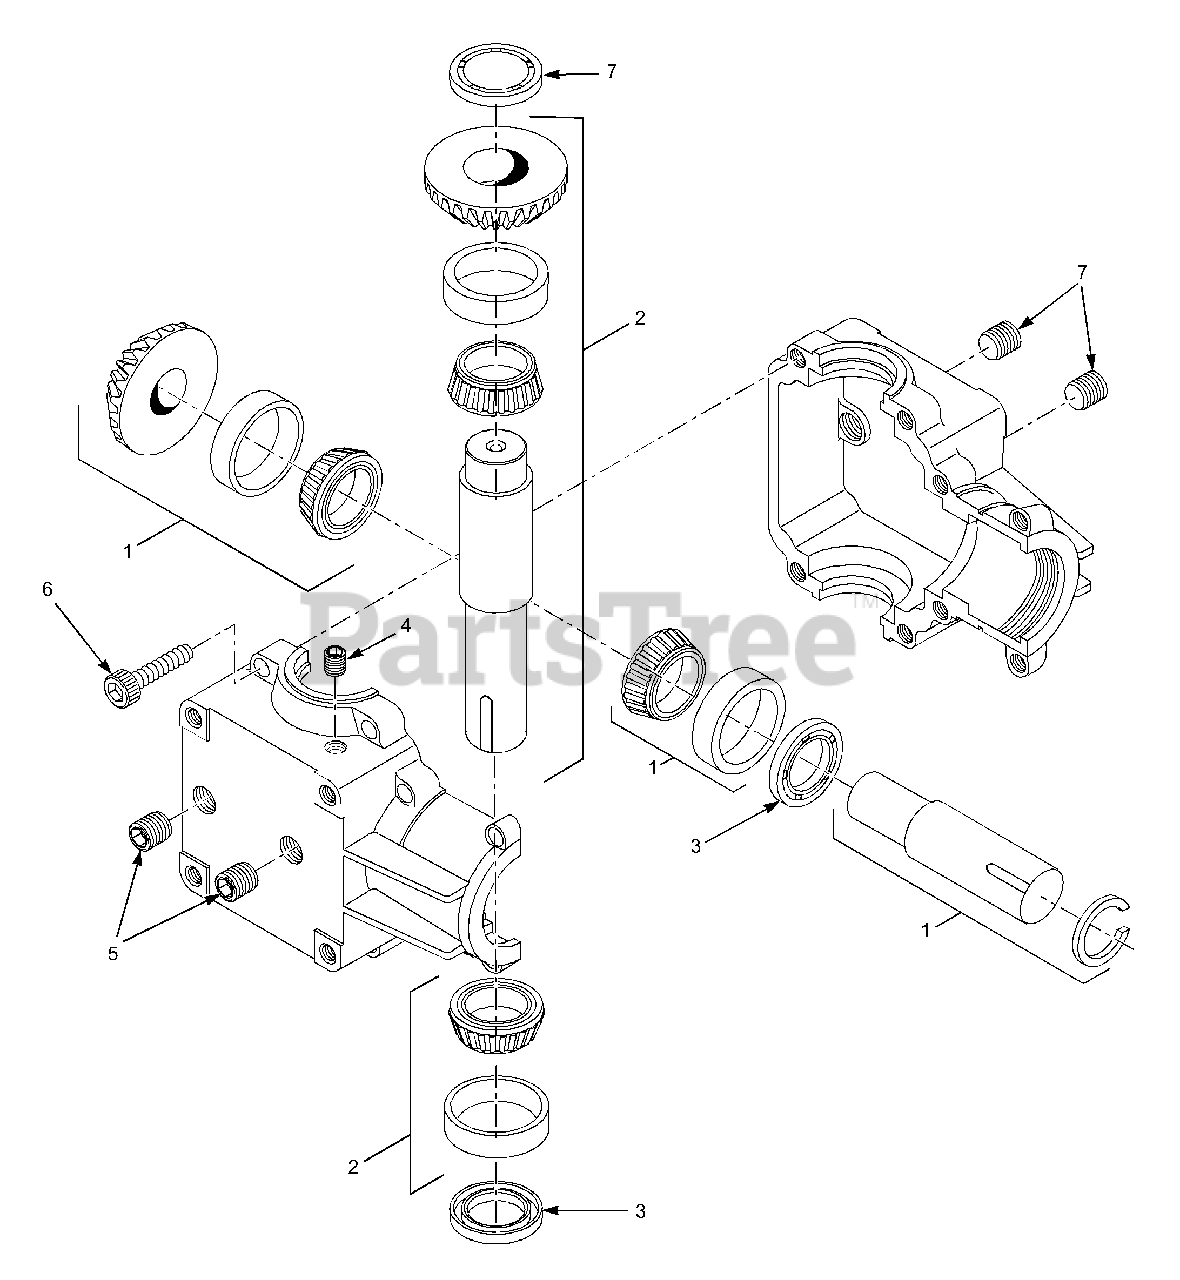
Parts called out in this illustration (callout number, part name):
1	Shaft Assembly
2	Shaft Assembly
3	Seal, 1.00" x 1.50" x 3/16"
4	Plug, 1/8" NPT Socket Head
5	Plug, 1/4" NPT Socket Head
6	Bolt, 5/16-18 x 1.25"
7	End Cap
